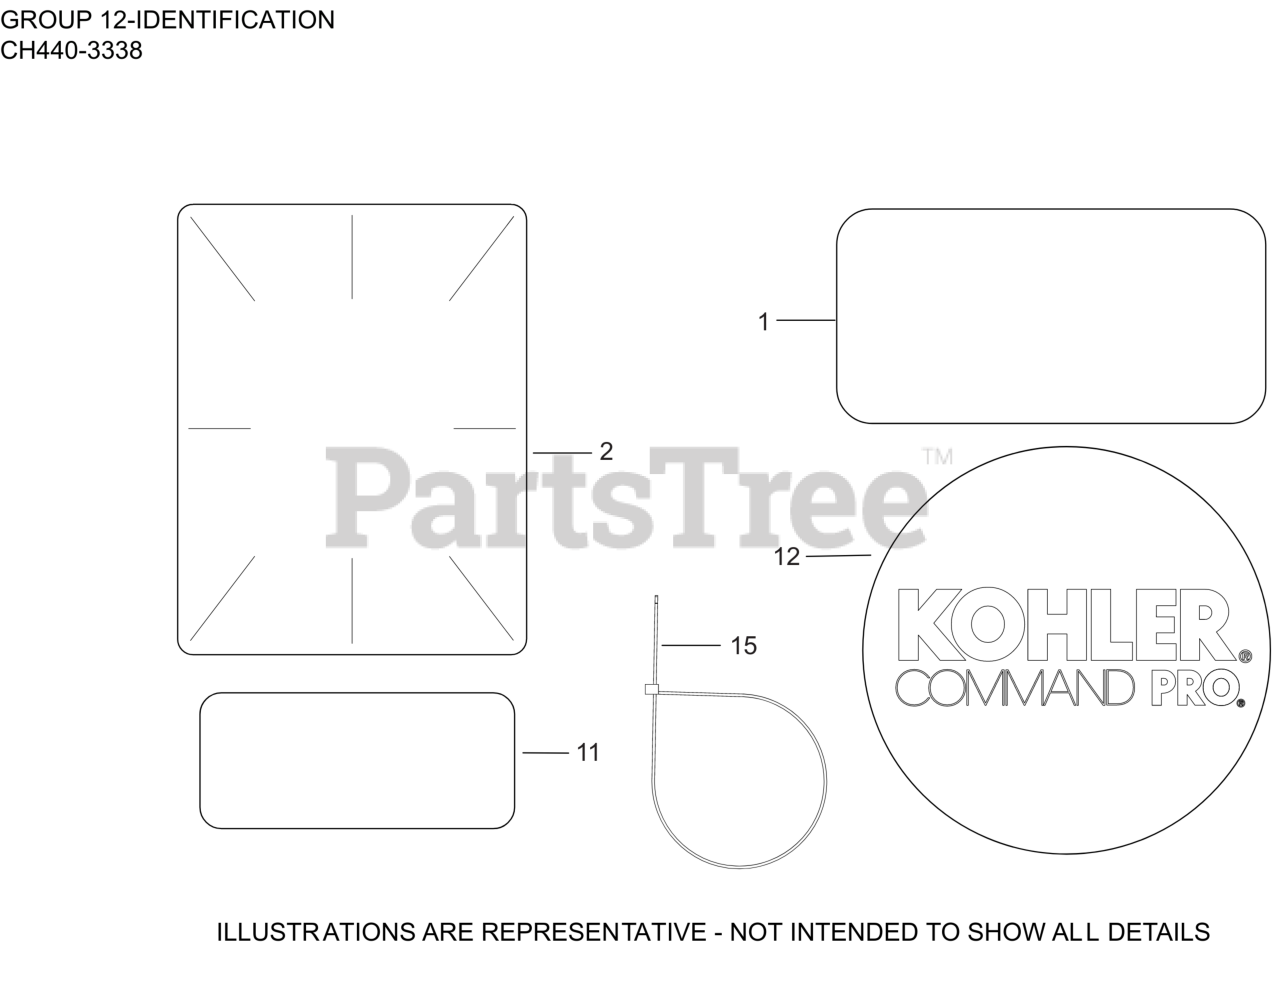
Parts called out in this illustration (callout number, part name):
1	LABEL, MAINTENANCE (CKY)
2	LABEL, CLEAR LAMINATION
11	LABEL, CANADIAN COMPLIANCE
12	LABEL, RECOIL 75MM
